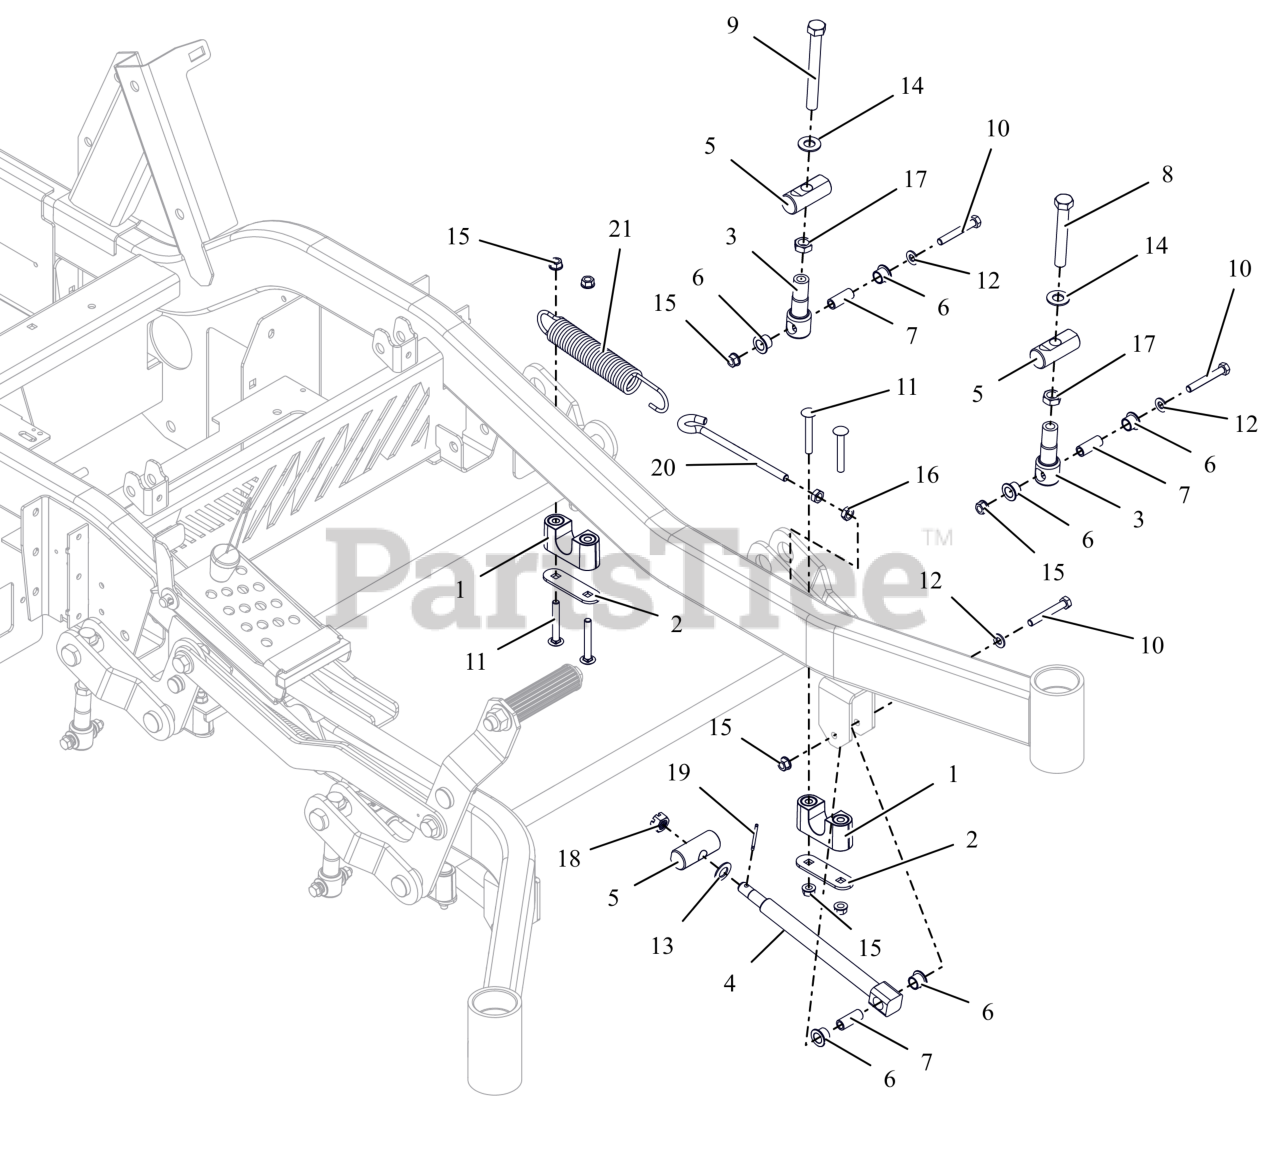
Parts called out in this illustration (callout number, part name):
1	ASM-BUSHING, DECK LIFT
2	PLATE, BEARING SUPPORT
3	LINK, DECK LIFT FORMED
4	DRAG,LINK-HD
5	PIN, DECK LIFT
6	BSHG, FLANGED .50X.625X.50X.062
7	SPCR, .31X.50X1.265
8	BLT, HEX 0.5-13X3.5F GR5 ZCC
9	BLT, HEX .50-13X4.50F G8 ZCC
10	BLT, HEX .31-18X2.25 G5 ZCC
11	BLT, RHSSN.31-18X2.25 G5 ZCC
12	WSHR,FLT .344X.688X.065 ZCC
13	WSHR, BLVL .505 X 1.000 X .073 ZCC
14	WSHR, FLT .557X1.040X.102 ZCC
15	NUT,LK-CTR-FLG .31-18 GF ZCC
16	NUT-JAM .375-16 G2 ZCC
17	NUT-JAM .500-13 G2 ZCC
18	NUT-SL .50-13
19	PIN,CTR.12X1.25EXTPRSQCT ZC120
20	BOLT,.38-16 X 5.25-.62 DIA EYE
21	SG-TENS .162X1.25X8.25 WLD 25
